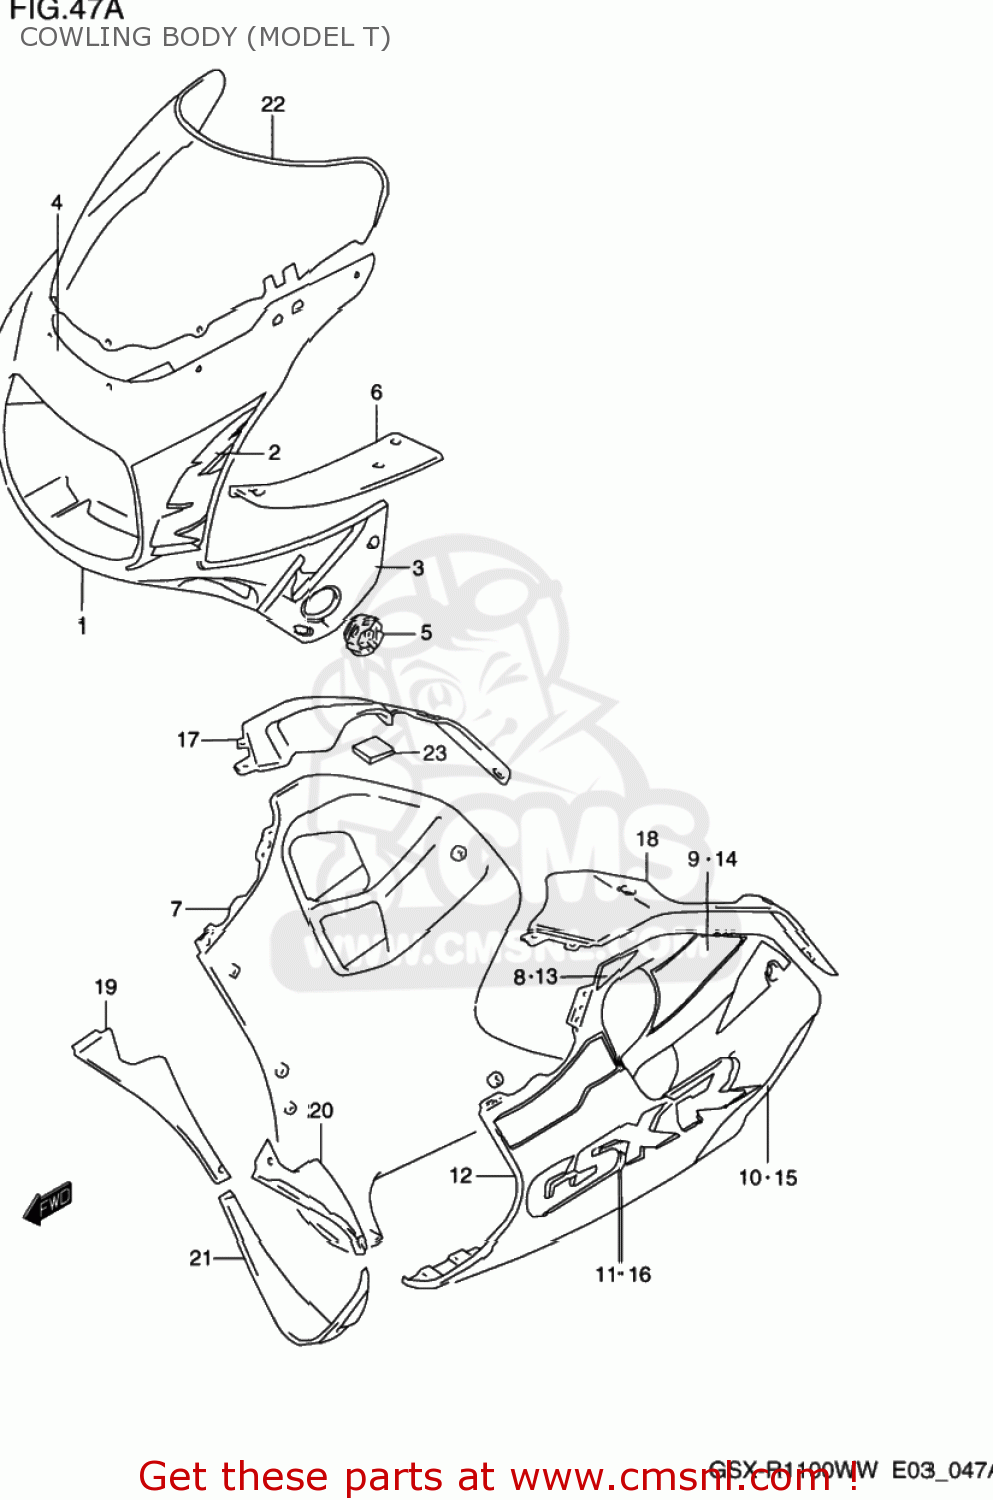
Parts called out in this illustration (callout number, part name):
1	COWLING ASSY,BODY
2	TAPE SET,BODY COWL FR
3	TAPE SET,BODY COWL SIDE
4	TAPE,BODY COWL
5	PLATE,TURN SIGNAL,RIGHT
6	PANEL,COWLING UPR,R
7	COWLING ASSY,UNDER,R
8	TAPE,COWL UNDER UPR,R
9	TAPE SET,COWL UNDER CTR,R
10	TAPE SET,COWL UNDER LWR,R
11	EMBLEM,COWLING UNDER,R
12	COWLING ASSY,UNDER,L
13	TAPE,COWL UNDER UPR,L
14	TAPE SET,COWL UNDER CTR,L
15	TAPE SET,COWL UNDER LWR,L
16	EMBLEM,COWLING UNDER,L
17	PANEL,LWR,R
18	PANEL,LWR,L
19	COWLING,UNDER INNER,R
20	COWLING,UNDER INNER,L
21	COWLING,UNDER CTR
22	SCREEN SET,WINDOW
23	CUSHION,CHAIN CASE
